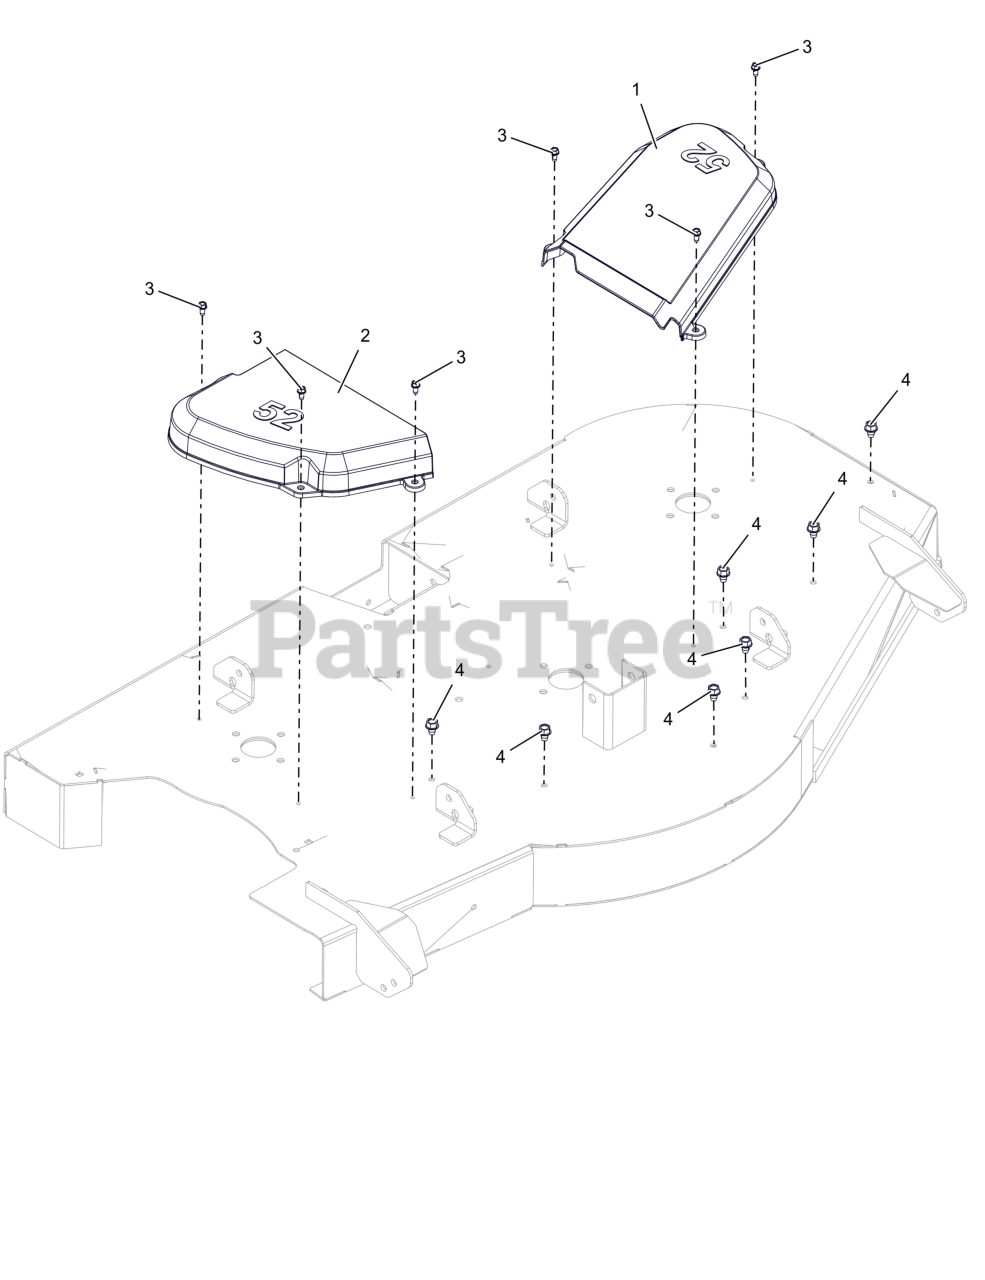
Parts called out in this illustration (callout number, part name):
1	COVER, BELT 52" LEFT
2	COVER, BELT 52" RIGHT
3	SCR-TAP .25-20X.50 HWH ZCC
4	SCR,TAP .375-16X.50 HWH TR ZCC
